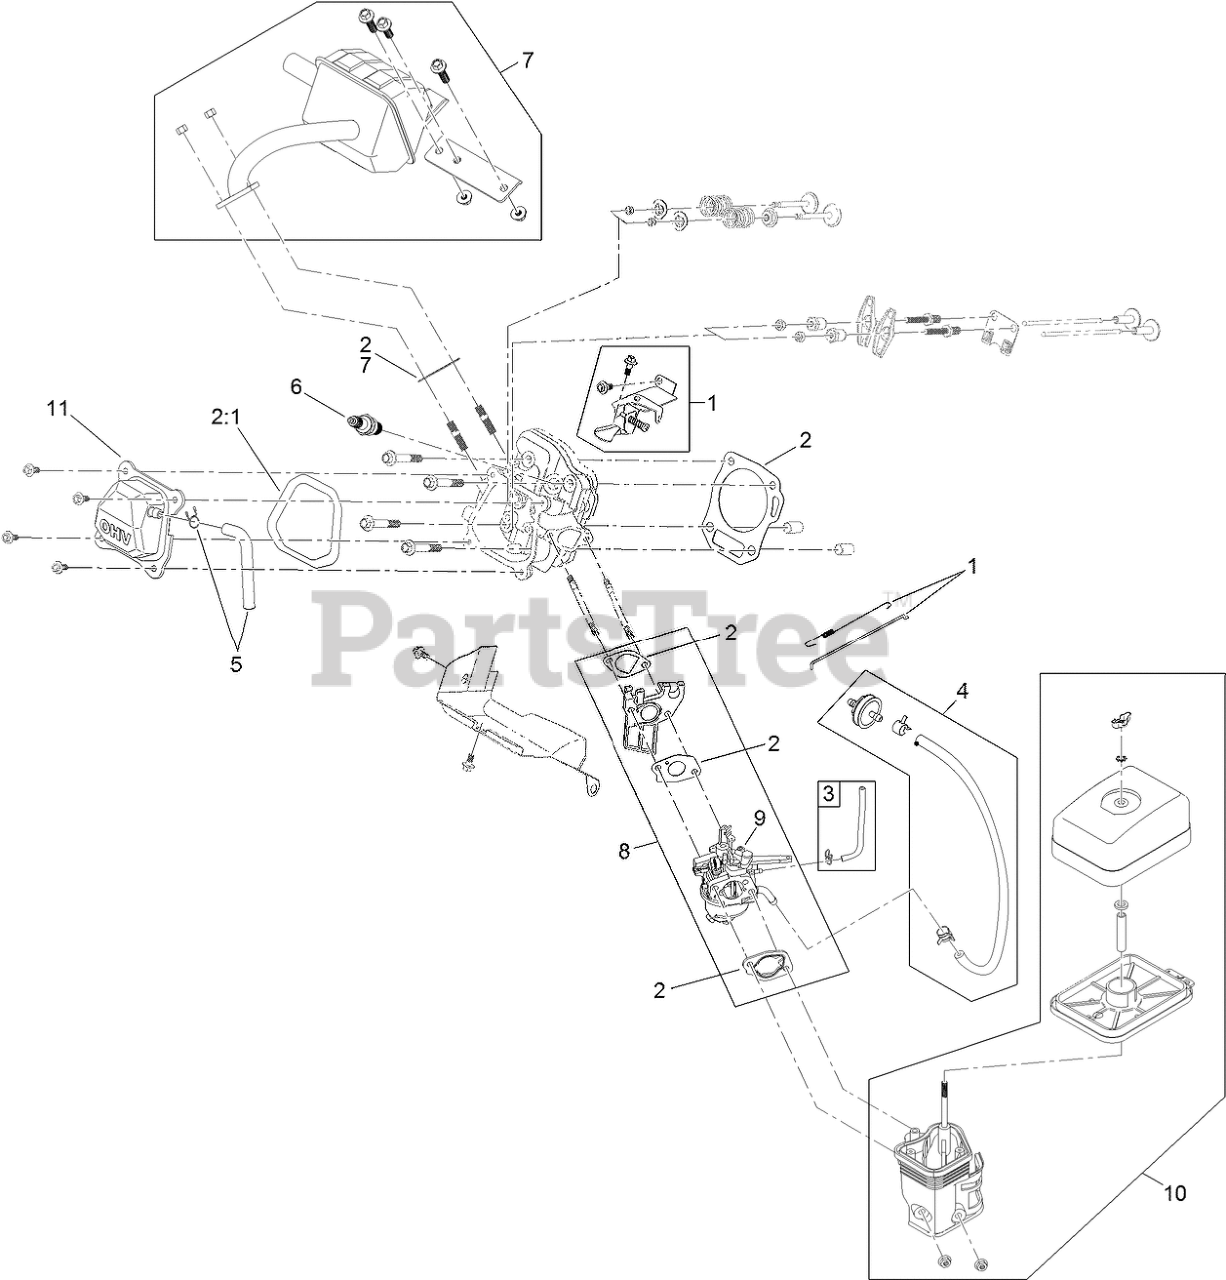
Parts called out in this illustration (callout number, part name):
1	GOVERNOR KIT
2	GASKET AND SEAL KIT
2:1	GASKET-COVER, VALVE
3	PRIMER LINE KIT
4	FUEL LINE KIT
5	BREATHER TUBE KIT
6	PLUG-SPARK
7	MUFFLER KIT
8	COMPLETE CARBURETOR SERVICE KIT
9	CARB FLOAT, VALVE AND GASKET KIT
10	HEATER BOX KIT
11	VALVE COVER ASM
